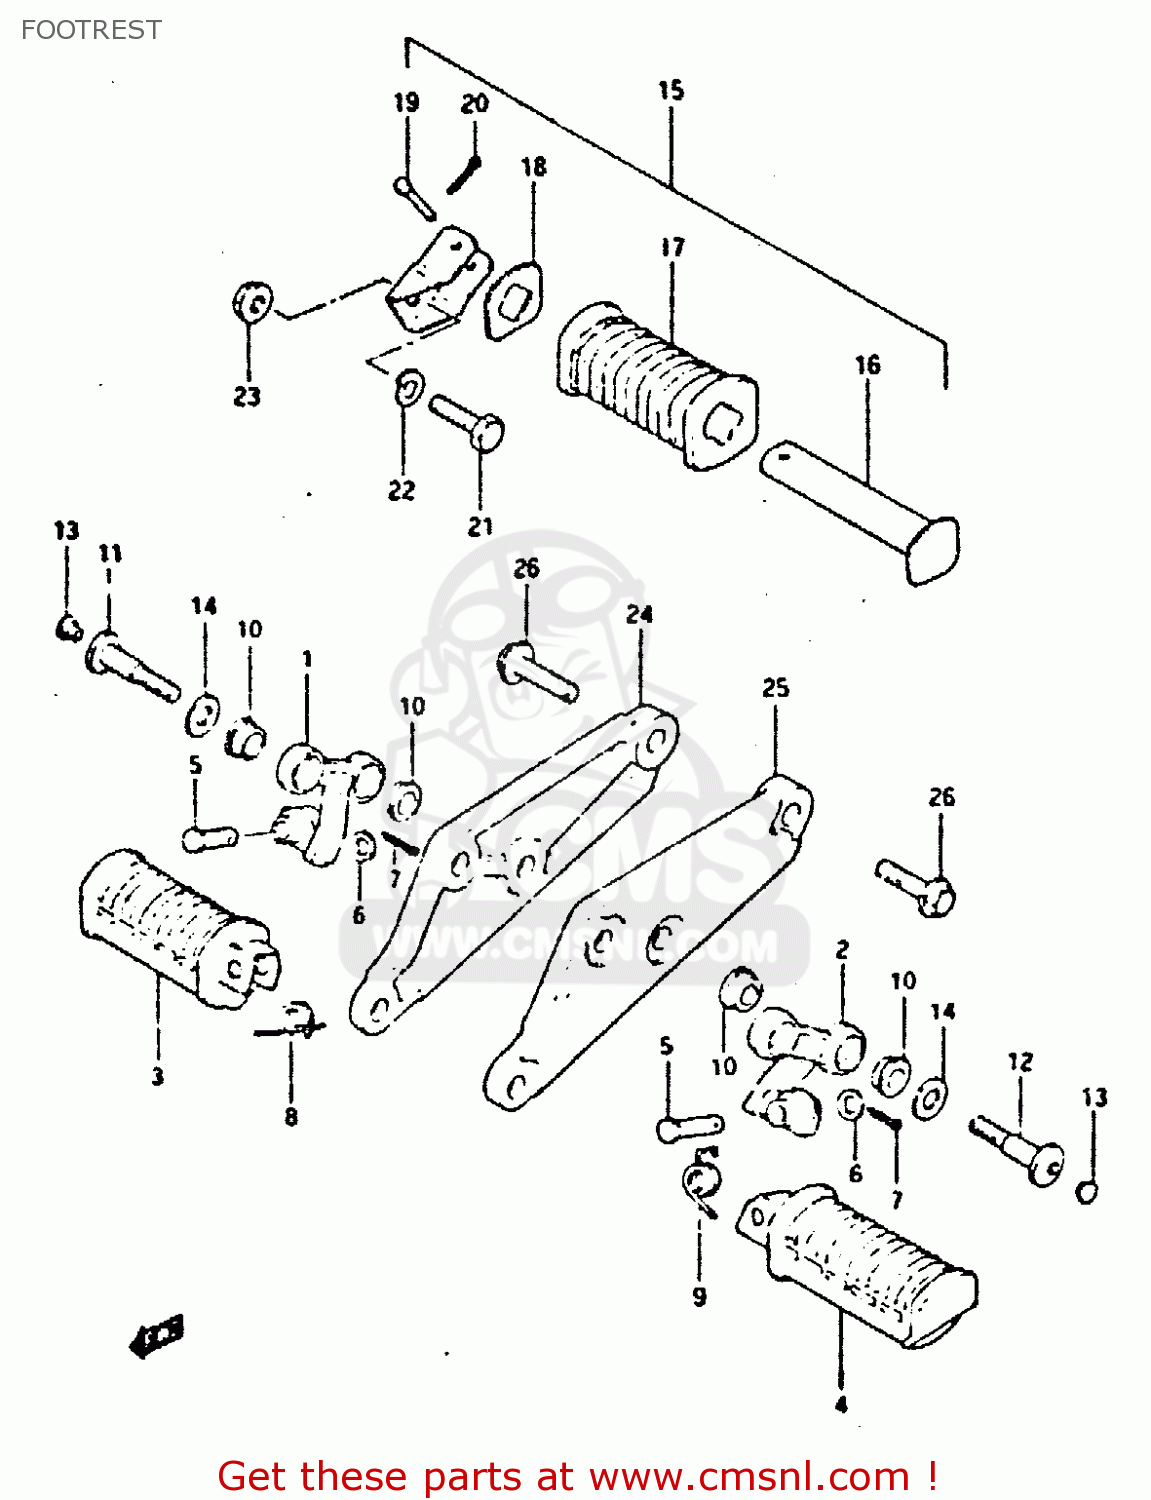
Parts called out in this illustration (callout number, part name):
1	BAR,FRONT FOOTREST,RIGHT
2	BAR,FRONT FOOTREST,LEFT
3	RUBBER,FOOTREST
4	FOOTREST
5	PIN
6	WASHER
7	PIN 20X20
8	SPRING
9	SPRING
10	BUSH
11	BOLT
12	BOLT
13	CAP
14	WASHER(10.5X28X2.3)
15	FOOTREST ASSY,PILLION,R
16	BAR,REAR FOOTREST,LEFT
17	RUBBER,PILLION FOOTREST
18	WASHER,FOOTREST RUBBER
19	PIN
20	PIN 20X20
21	BOLT,M10X1.25X
22	LOCK WASHER
23	NUT
24	BRACKET,MUFFLER,RIGHT
25	BRACKET,MUFFLER,LEFT
26	BOLT
